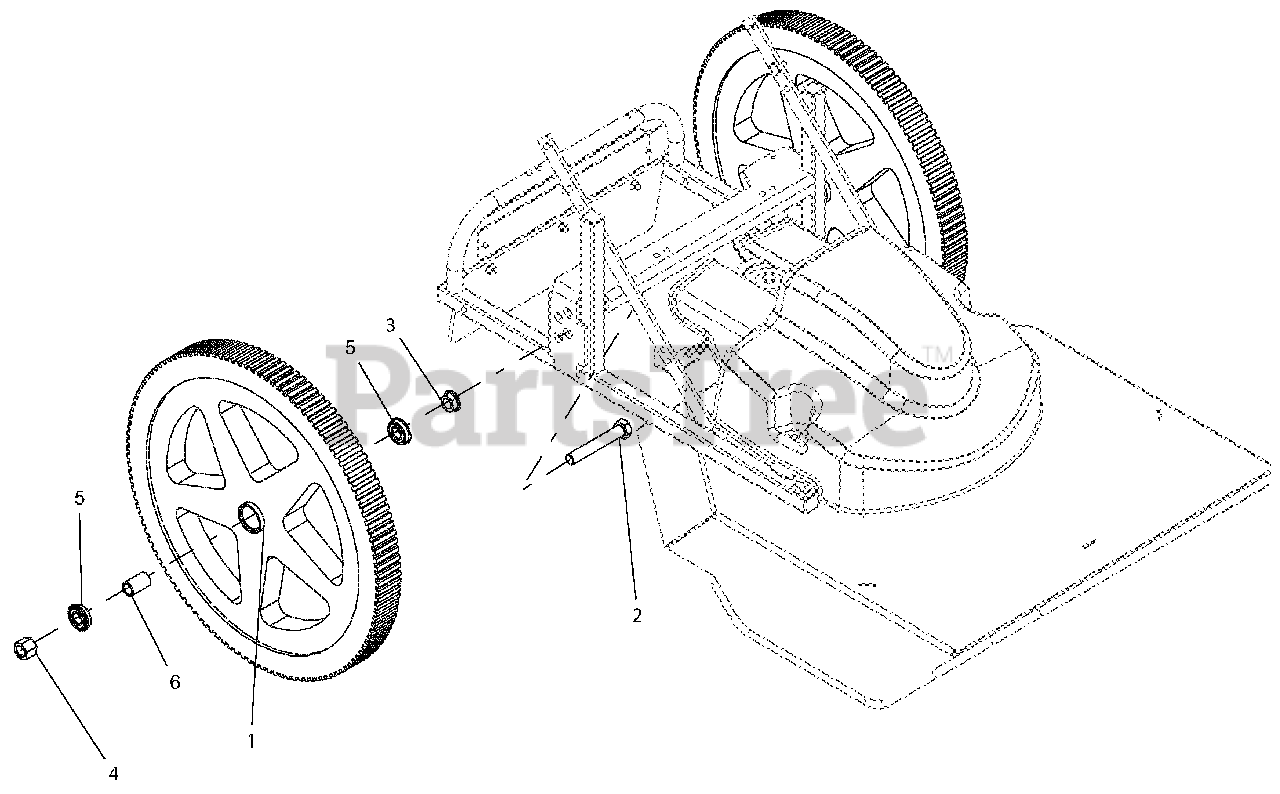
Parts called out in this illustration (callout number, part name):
1	WHEEL/TIRE ASSY, 20" SOLID RBBR
2	BLT-HEX .62-11X4.00 GR5 FTH YZ
3	NUT-HEX FLANGE .62-11 GR5 YWZC
4	NUT-LK-NYL .625-11 YWZC
5	BALL BEARING 5/8 ID X 1-3/8OD
6	SPCR, .640X.840X1.39
